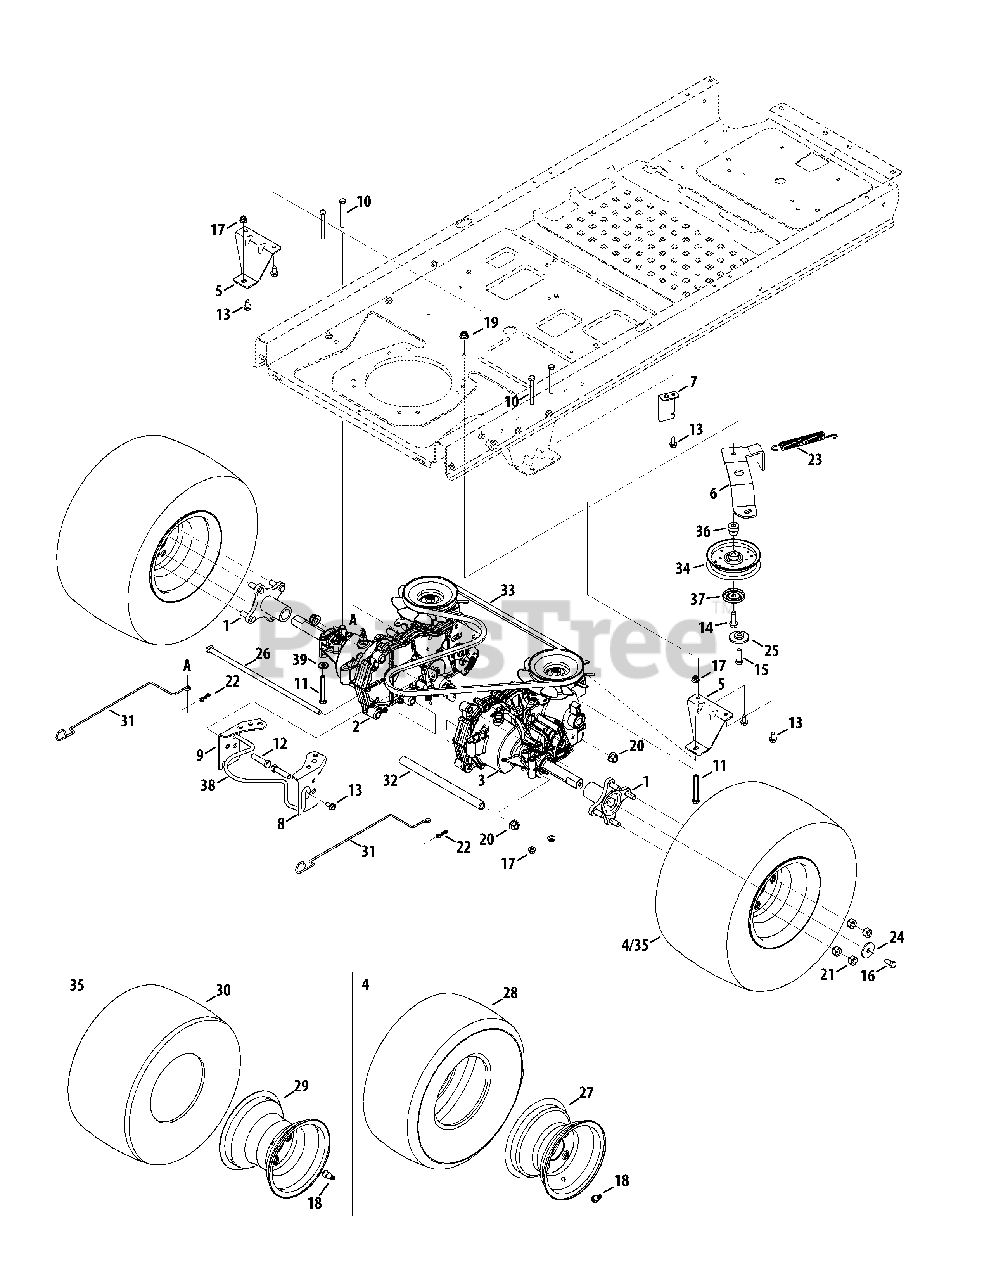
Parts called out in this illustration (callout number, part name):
1	Wheel Hub Assembly
2	Transmission Assembly, LH
3	Transmission Assembly, RH
4	Complete Wheel, 18 x 8.5-8 -Grey (42")
5	Transmission Mounting Bracket
6	Idler Bracket
7	Spring Mounting Bracket
8	Transmission Bracket
9	Transmission Bracket
10	Hex Screw 5/16-18 x 2.75
11	Screw-HHCS 5/16-18 x 2.25
12	Hex Screw 7/16-20 x 1.75
13	Hex Washer Screw 5/16-18 x .750
14	Hex Washer Screw 3/8-16 x 1.250
15	Hex Screw 3/8-16 x 1.00
16	Hex Screw 3/8-16 x .75
17	Flange Lock Nut 5/16-18
18	Valve Tubeless
19	Jam Lock Nut 3/8-16
20	Flange Lock Nut 7/16-20
21	Lug Nut 7/16-14
22	Bow-Tie Cotter Pin
23	Extension Spring .75 Dia. x 6.02
24	Flat Washer .390 x 1.50 x .134
25	Shoulder Spacer .884 x .190
26	Rod .405 Dia. x 14.0 Lg.
27	Rim Only (42")
28	Tire Only 18 x 8.5-8 (42")
29	Rim Only (50" & 54")
30	Tire Only 18 x 9.5-8 (50" & 54")
31	Bypass Rod
32	Tube .51 ID x .75 OD x 10.2
33	Belt A-Type x 67.0
34	Idler Pulley 4.25 Dia.
35	Complete Wheel, 18 x 9.5-8 (50" & 54")
36	Shoulder Spacer
37	Pulley Cap
38	Engine Keeper Rod (42" deck)
38	Engine Keeper Rod (50" & 54" deck)
39	Flat Washer .330 x .630 x .064
